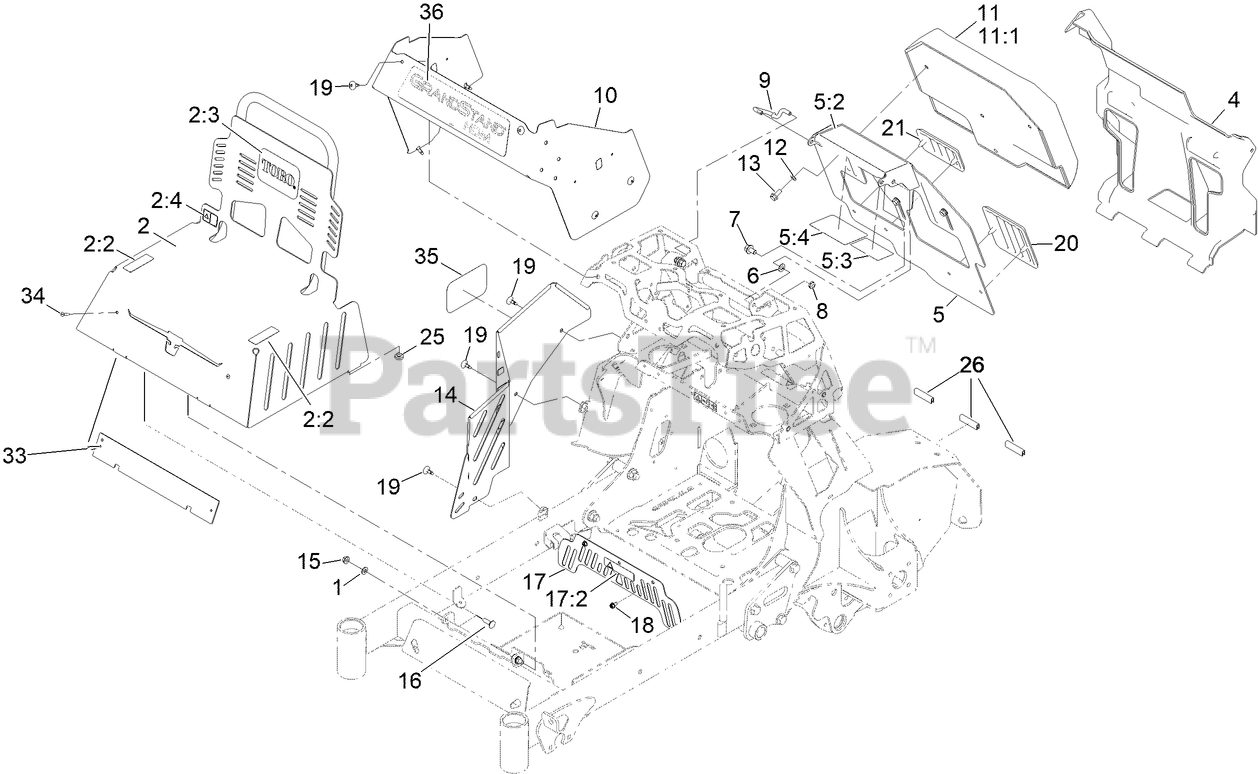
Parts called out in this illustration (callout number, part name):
1	SPACER-NYLON
2	ENGINE GUARD W/DECALS
2:2	DECAL-NO STEP/RIDERS
2:4	DECAL-WARNING
4	COVER-REAR STE
5	ASM, PAD BACKING W/ DECALS
5:2	DECAL-WARNING
5:3	DECAL-DRIVE RELEASE
5:4	DECAL-SERVICE AID SM
6	WASHER-THRUST
7	SCREW-HHF
9	ROD, PROP
10	SKIN TOWER
11	PAD-THIGH
11:1	COVER PAD
12	WASHER-BELLEVILLE
13	SCREW-HHF
14	COVER RT SIDE
15	NUT-HF
16	BOLT-CARR
17	ASM, BELT GUARD W/ DECAL
17:2	DECAL-WARNING
18	SCREW-HWH
19	SCREW, TORX
20	PAD, KNEE, LT
21	PAD, KNEE, RT
25	BUMPER
26	STRIP-SEAL 2.13
33	PLATE-BACKER
34	RIVET-TRIFOLD
36	DECAL-GRADSTAND HDM
